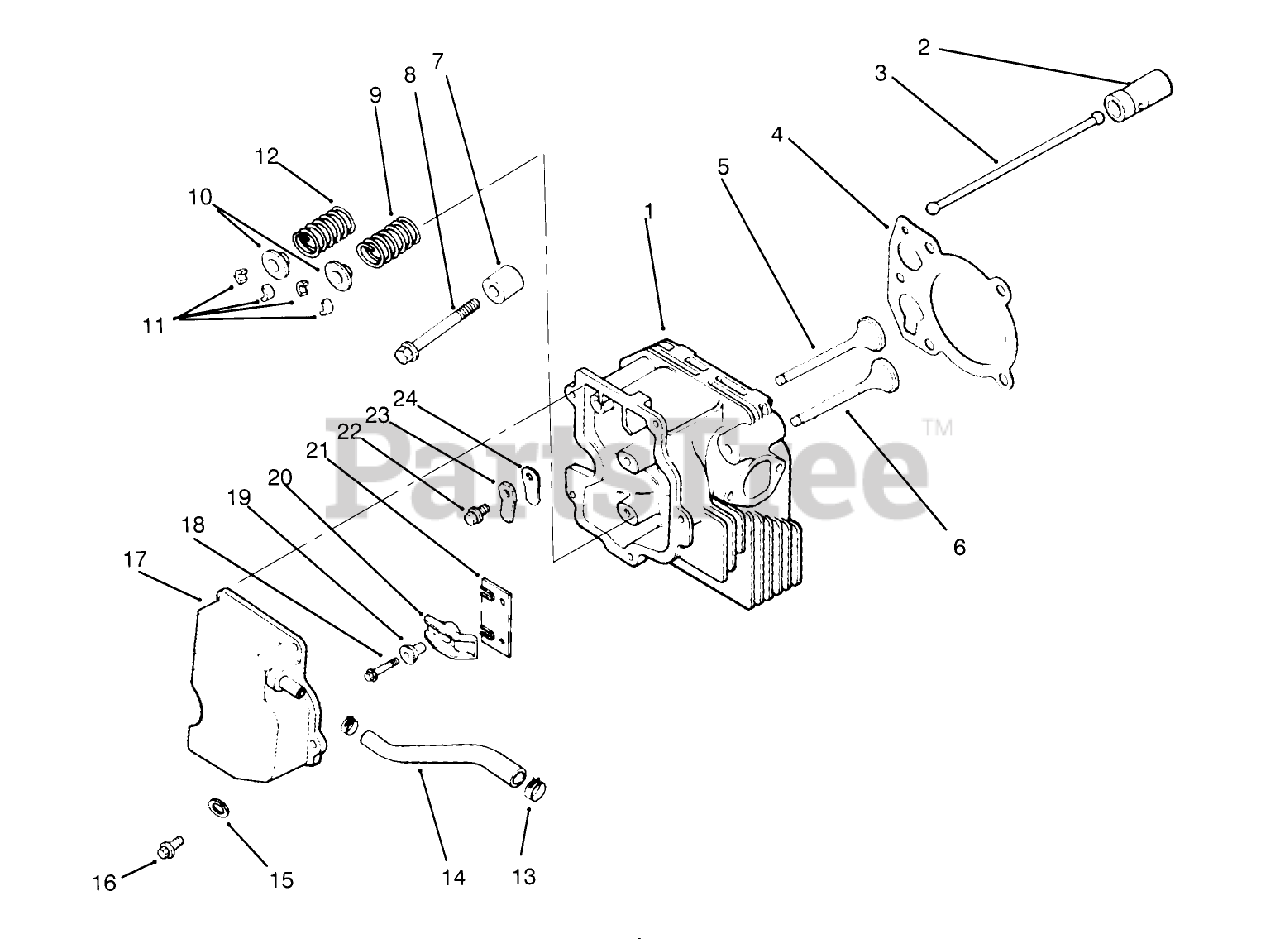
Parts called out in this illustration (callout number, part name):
1	Cylinder Head (Only On: 72042,72043,72062,72063)
2	Lifter-Valve
3	Rod-Push (Only On: 72042,72043,72062,72063)
4	Gasket-Cylinder Head (Only On: 72042, 72063, 72062, 72043)
5	Valve-Intake STD (Only On: 72042, 72063, 72062, 72043)
5	Valve-Intake .25 (Only On: 72042,72043,72062,72063)
6	Valve-Exhaust STD (Only On: 72042,72043,72062,72063)
6	Valve-Exhaust .25 (Only On: 72042, 72063, 72062, 72043)
7	Spacer-Head Bolt Exhaust (Only On: 72042, 72063, 72062, 72043)
8	Screw M10x1.5x80 (Only On: 72042, 72063, 72062, 72043)
9	Spring-Valve Exhaust (Only On: 72042,72043,72062,72063)
10	Cap-Valve Spring
11	Kit-Retainer
12	Spring-Valve Intake (Only On: 72042, 72063, 72062, 72043)
13	Clamp
14	Hose-Breather (Only On: 72042, 72063, 72062, 72043)
15	Washer-Flat (Only On: 72042, 72063, 72062, 72043)
17	Cover-Valve W/Nipple (Only On: 72042, 72063, 72062, 72043)
19	Ball-Rocker Pivot
20	Arm-Rocker
21	Plate-Guide (Only On: 72042, 72063, 72062, 72043)
23	Retainer-Reed
